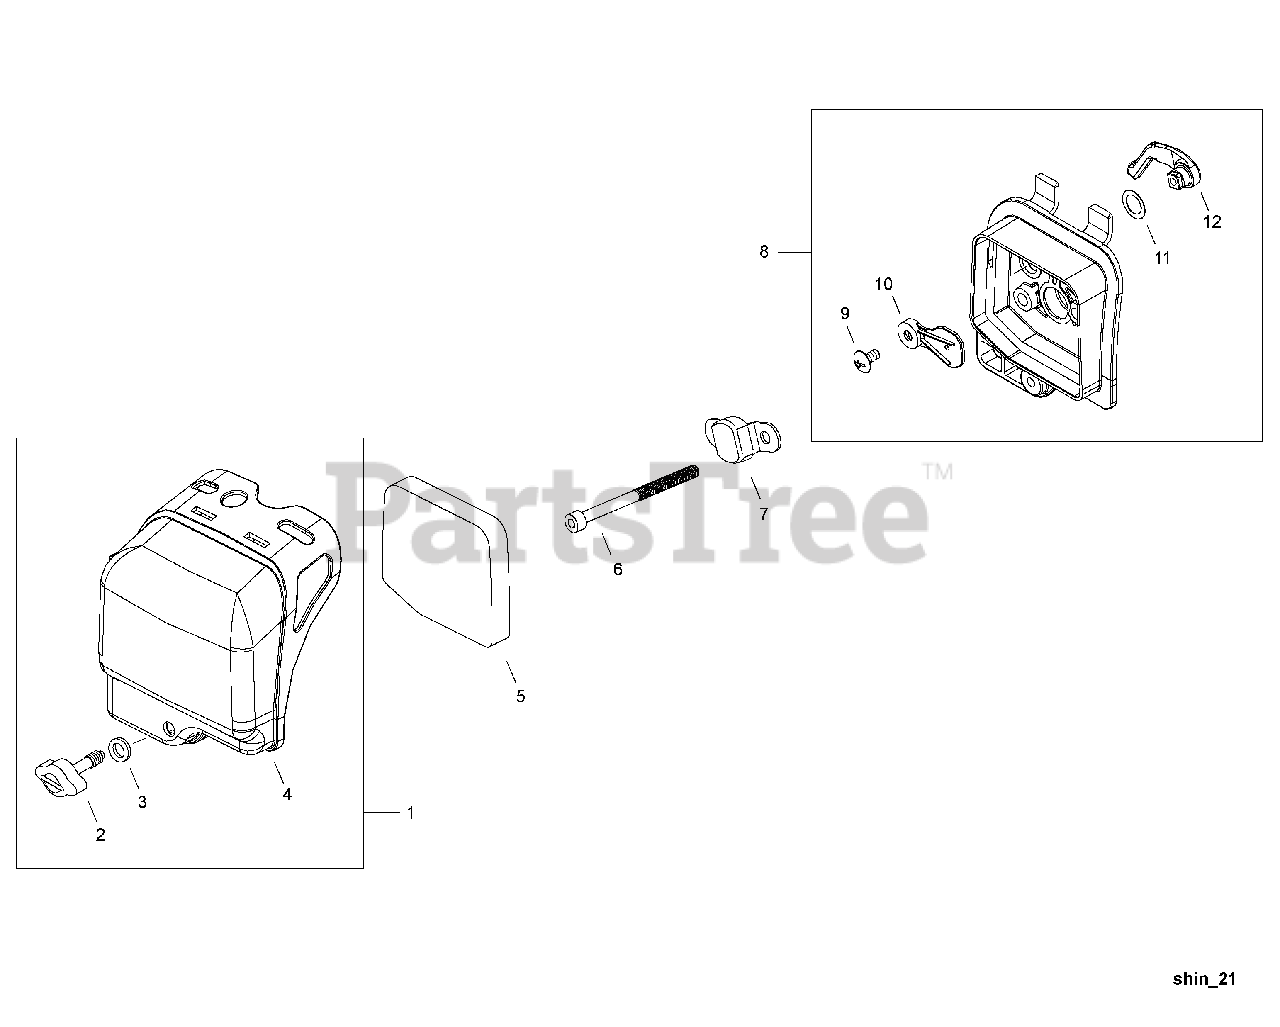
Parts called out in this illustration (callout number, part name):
1	AIR FILTER COVER ASSY
2	THUMBSCREW
3	WASHER - VINYL
4	COVER, AIR FILTER
5	FILTER, AIR
6	SCREW - 5X60
7	PLATE, PREVENT
8	CASE, AIR FILTER
9	SCREW - 4X12
10	PLATE, CHOKE
11	WASHER - SPRING
12	LEVER, CHOKE
